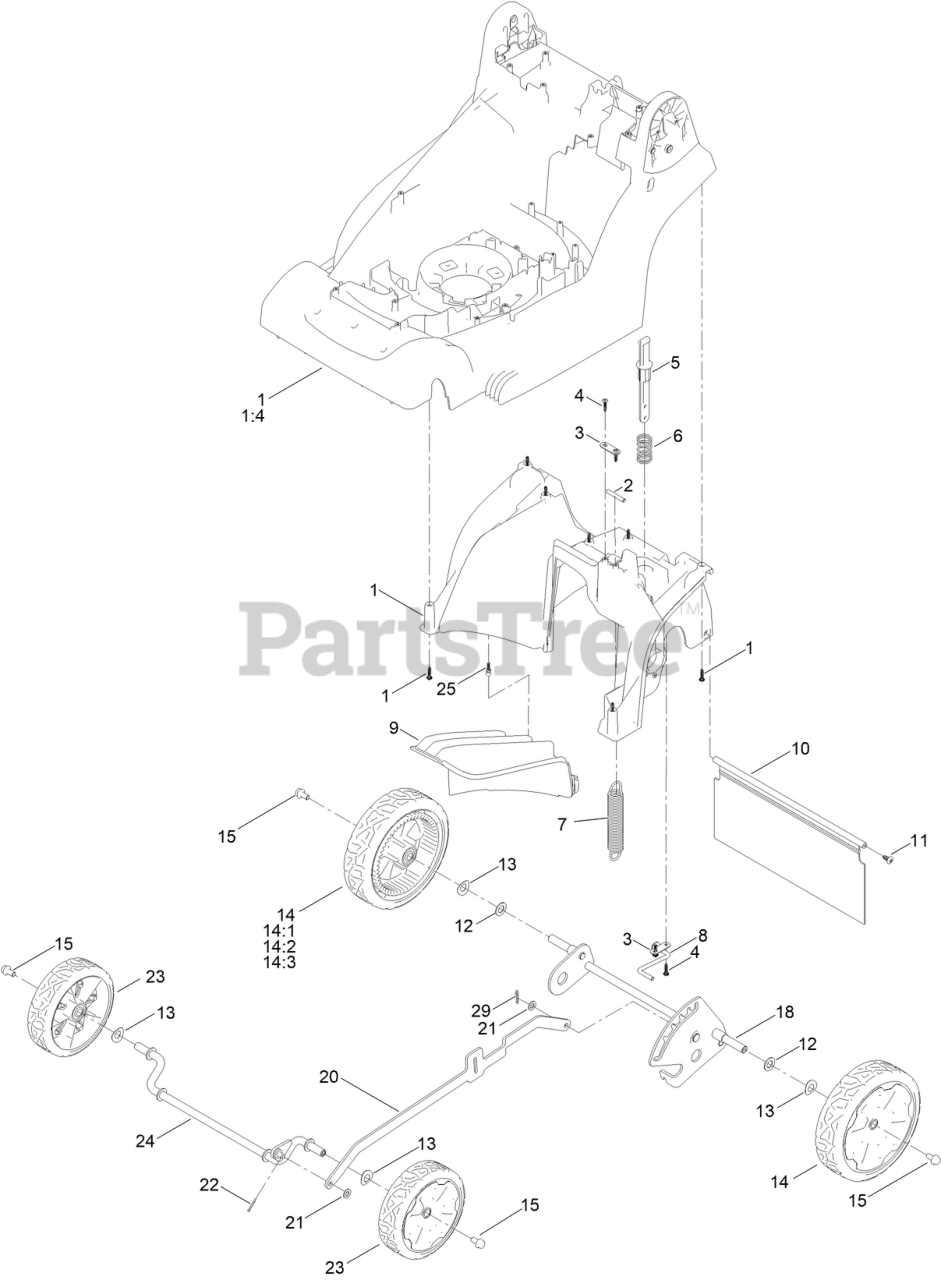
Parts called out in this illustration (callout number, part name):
1	DECK, GLUED (43)
1:4	DECAL - SAFETY
2	BAR, SPRING MOUNT
3	AXLE PLATE, SMALL
5	HOC BUTTON PLUNGER
6	SPRING, HOC BUTTON
7	HOC SPRING, 4 WHEEL
8	HOC WIRE ASM
9	MULCH PLUG
10	SHIELD-TRAILING
11	SCREW-PTH
12	WASHER-PLAIN
13	WAVE WASHER, FRONT WHEELS
14	WHEEL-REAR ASSEMBLY
14:1	WHEEL-TORO REAR
14:2	BEARING
14:3	REAR WHEEL TRIM - TORO
15	BOLT, M8 X 1.25, 16MM
18	REAR AXLE FRAME, ASSY, WHEEL
20	Cover, Exhaust-Right
21	WASHER-PLAIN
22	COTTER PIN
23	WHEEL-TORO FRONT ASSEMBLY
24	FRONT AXLE, ASSEMBLY
25	PIN, RETAINING, MULCH PLUG
29	COTTER PIN
